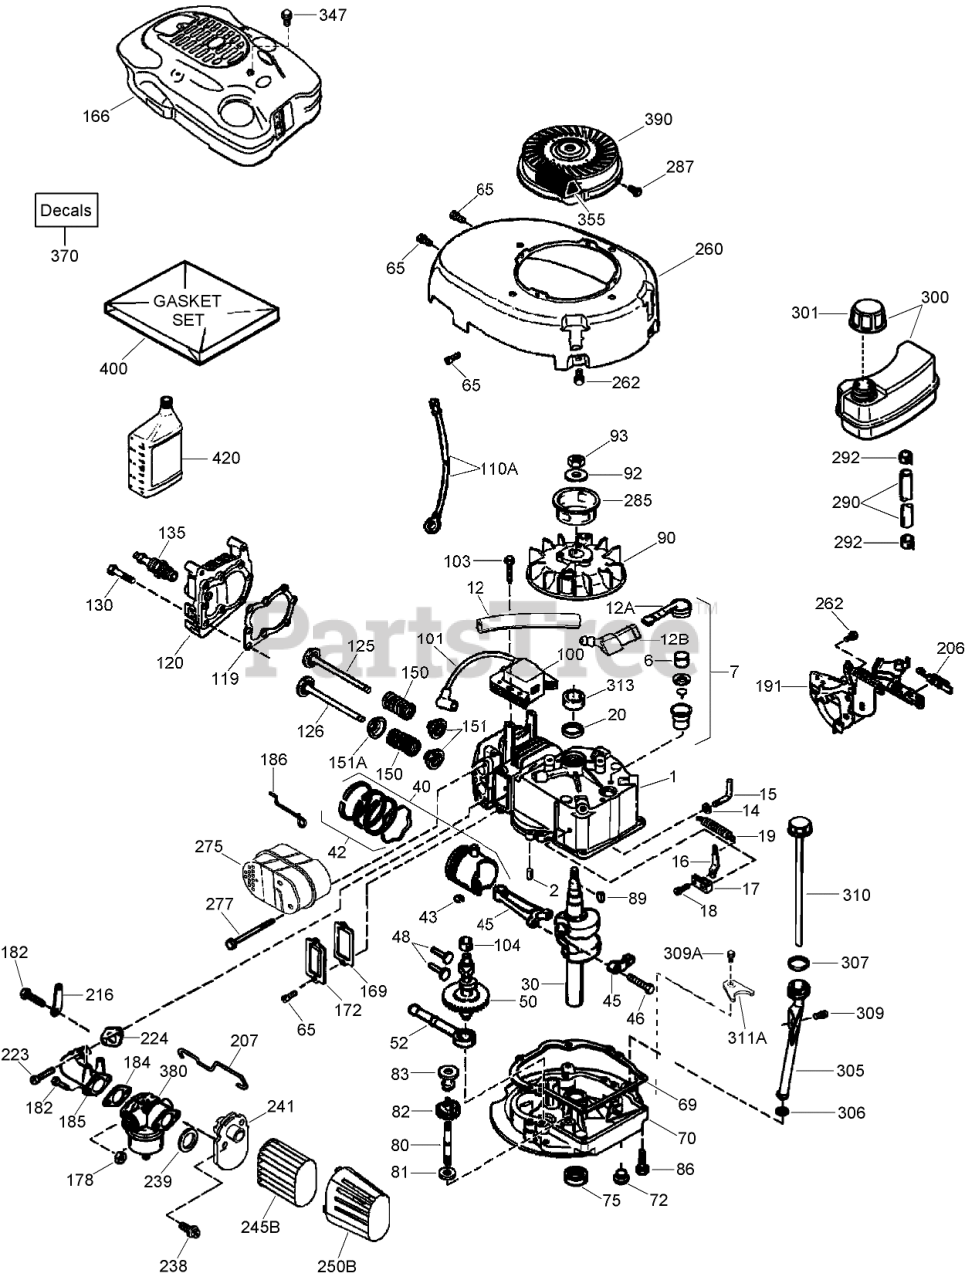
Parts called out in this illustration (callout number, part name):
1	Cylinder Asm (Includes 2, 20)
2	Pin-Dowel
6	Element-Breather
7	Breather Asm (Includes 6, 12A)
12	Tube-Breather
12A	Breather Cover and Tube ASM
12B	Elbow-Tube, Breather
14	Washer-Flat
15	Governor Rod Asm (Includes 14)
16	Lever-Governor
17	Clamp-Lever, Governor
18	Screw (T-15, 8-32 x 19/64)
19	Spring-Extension
20	Seal-Oil
30	Crankshaft
40	Piston, Pin and Ring Set (.010 O S) (Includes 42)
40	Piston, Pin and Ring Set (Std) (Includes 42)
42	Ring Set (.010 O S)
42	Ring Set (STD)
43	Ring-Retaining, Piston Pin
45	Connecting Rod Asm (Includes 46)
46	Bolt-Rod, Connecting
48	Lifter-Valve
50	Camshaft (Exhaust M C R) (Includes 104)
52	Oil Pump ASM
65	Screw (10-24 x 9/16)
69	Gasket-Flange, Mounting
70	Mounting Flange Asm (Includes 72-83, 306, 309A, 311A)
72	Plug-Drain, Oil (Flush Mount)
75	Seal-Oil
80	Shaft-Governor
81	Washer-Flat
82	Governor Gear Asm (Includes 81)
83	Spool-Governor
86	Screw (1/4-20 x 1-1/4)
89	Key-Flywheel
90	Flywheel
92	Washer-Belleville
93	Nut-Flywheel
100	Ignition-State, Solid
101	Cover-Spark Plug
103	Screw (T-15, 10-24 x 15/16)
104	Bushing-Cam
110A	Wire-Ground
119	Gasket-Head, Cylinder
120	Head-Cylinder
125	Exhaust Valve (Std) (Includes 151)
126	Intake Valve (Std) (Includes 151)
130	Screw (5/16-18x1-1/2)
